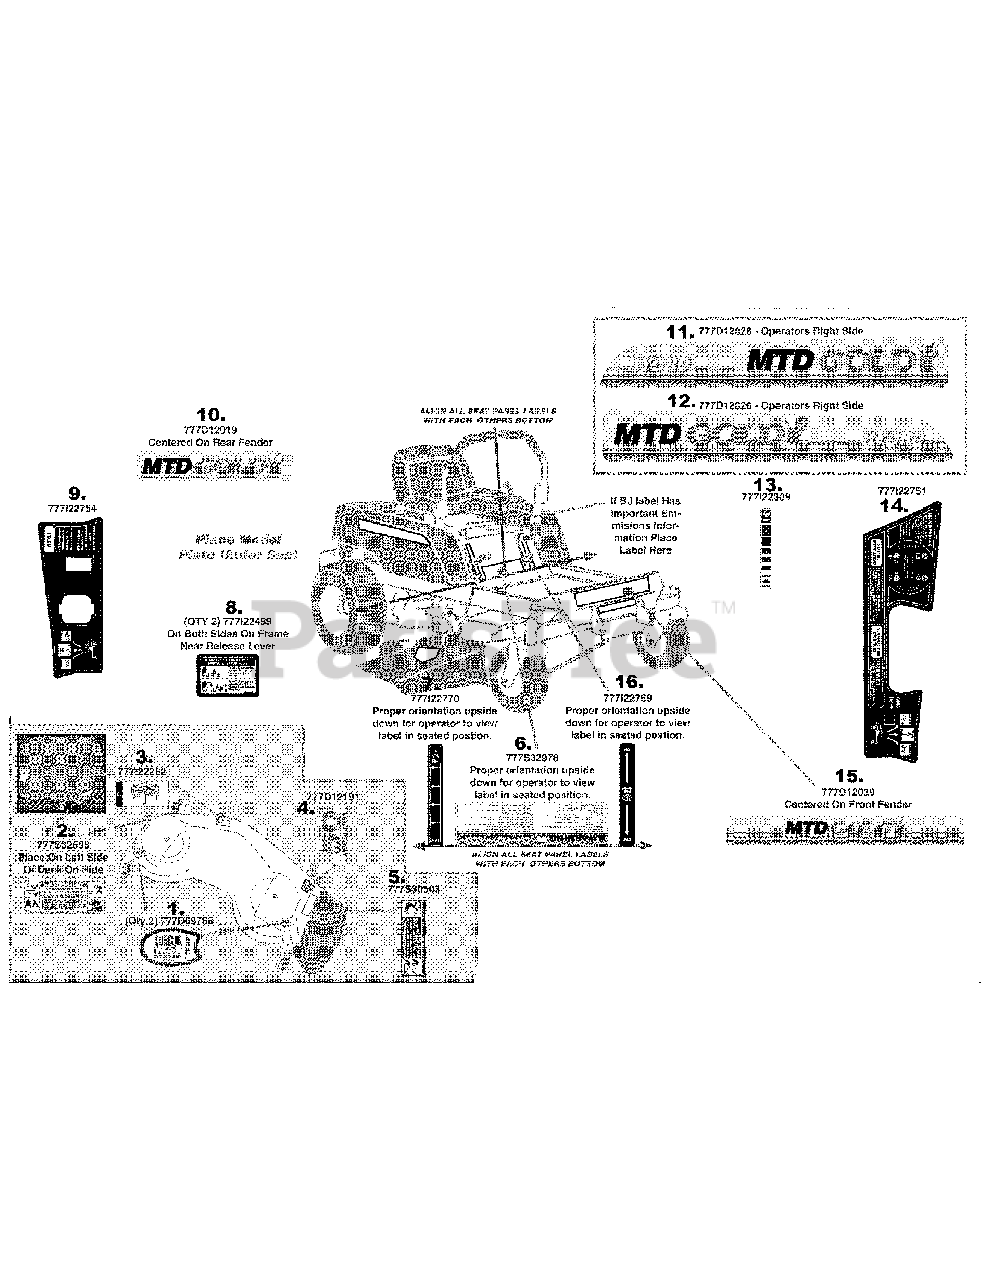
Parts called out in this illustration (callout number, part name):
1	LABEL:RIDER:WHITE
2	LABEL-RZT DECK WARNG STRAIGHT
3	LABEL-BELT ROUTE
4	LABEL-RZT DECK 50"
5	LABEL-DANGER CHUTE
6	LABEL-COMMON WARNING
7	LABEL-HANDLE HEIGHT
8	LABEL-TRNMSN RELEASE
9	LABEL-RH CONTROL
10	LABEL-RIDER REAR FENDER MTD GOLD
11	LABEL-RZT POD MTD GOLD LH
12	LABEL-RZT POD MTD GOLD RH
13	LABEL-THROTTLE
14	LABEL-LH CONTROL W/CHOKE
15	LABEL-RZT FRONT MTD GOLD
16	LABEL-PARK BRAKE
